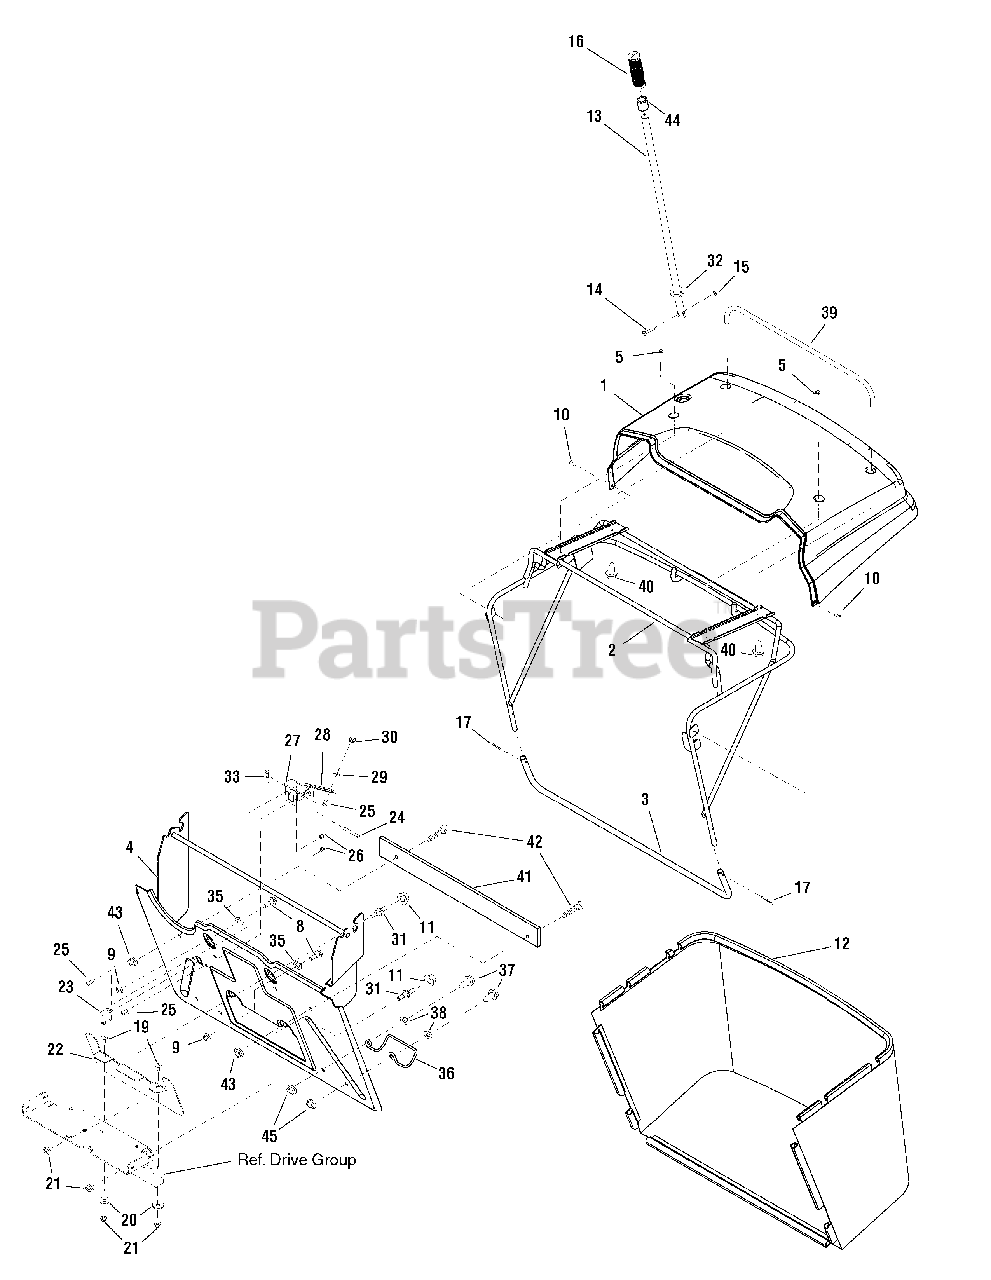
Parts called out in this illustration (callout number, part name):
1	BAGGER COVER (Red)
2	BAG FRAME ASSY
3	BAG FRAME, Lower
4	REAR PLATE ASSY
5	SCREW, Self Tap
8	CAPSCREW, 3/8-16 x 1 1/4
9	NUT, 3/8-16
10	SCREW, Flat Head 10-3/4
11	NUT, Flange, 5/16-18
12	BAG
13	HANDLE, Bagger
14	SCREW, 1/4-20 x 1.25
15	NUT, Hex Flange Lock, 1/4-20
16	GRIP
17	COTTER PIN
19	BOLT, Carriage, 3/8-16 x 5/8
20	WASHER, 0.406 x 1 1/4
21	NUT, 5/16-18
22	BAFFLE, Rubber
23	SWITCH, Bag Full
24	PIN
25	BOLT, Carriage, 1/4-20 x 5/8
26	NUT, Hex, 1/4-20
27	BRACKET, Bag Full
28	LEVER, Bag Full Indicator
29	WASHER, .26 X.75 X 16GA
30	WINGNUT
31	SCREW, Self Tapping, 5/16-18 x 1.13
32	WASHER, Flat 1.862 x .765 x 16GA
33	HAIRPIN
35	WASHER, .39-1.14
36	LATCH, Spring
37	CAPSCREW, Hex Whiz Lock Flange, 5/16-18 x 3/4
38	WASHER, .391 x 0.62 x.03
39	HANDLE, Bagger
40	SCREW, 1/4 - 20 x 5/8
41	BRACE
42	CAPSCREW, Hex Head, 3/8-16 x 1-1/4
43	NUT, 3/8-16
44	HEIGHT ADJUSTER
45	NUT, Hex Flange Serrated, 5/16-18
